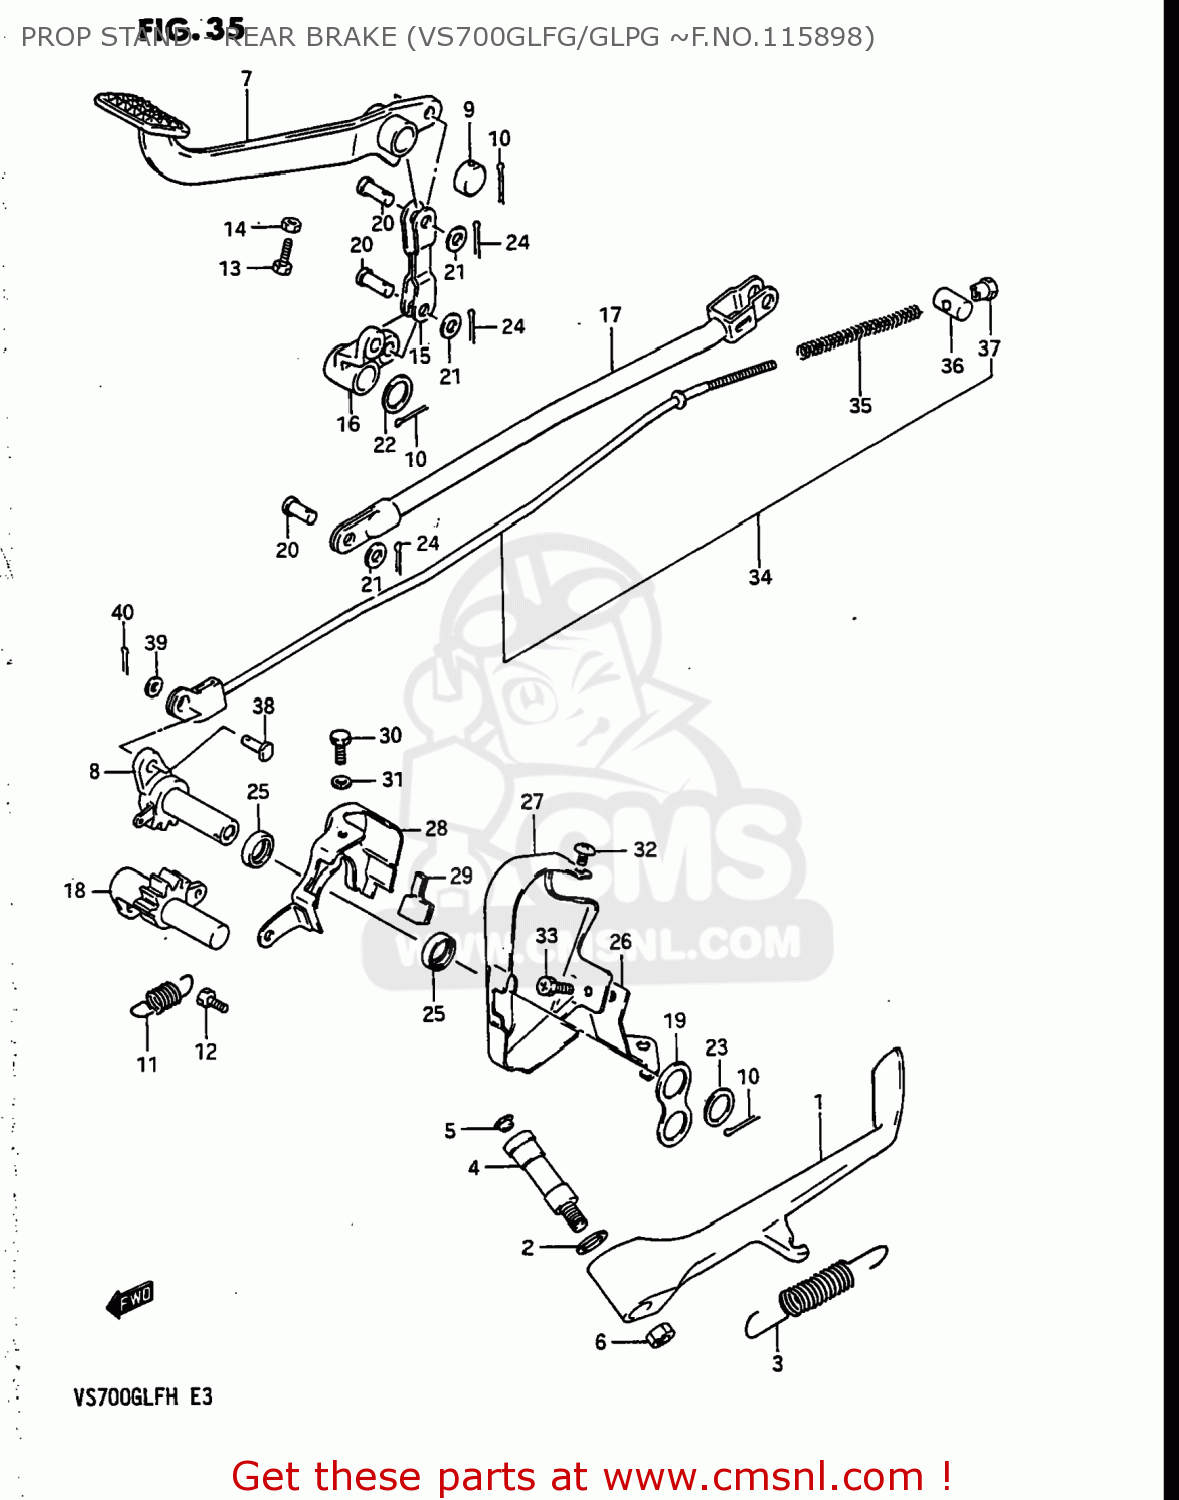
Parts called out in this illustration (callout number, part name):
1	STAND,PROP
2	THRUST WASHER
3	SPRING
4	BOLT,PROP STAND
5	CAP
6	NUT
7	PEDAL ASSEMBLY,BRAKE
8	ARM COMP,BRAKE ROD
9	CAP,BRAKE PEDAL
10	COTTER PIN
11	SPRING
12	ARM,BRAKE PEDAL LINK
13	BOLT
14	NUT
15	LINK COMP,BRAKE ROD NO
16	ARM,BRAKE PEDAL LINK
17	LINK COMP,BRAKE NO.2
18	ARM COMP,BRAKE PEDAL,LEFT
19	PLATE,BRAKE PEDAL ARM
20	PIN
21	WASHER
22	WASHER (16.5X42X2.6)
23	WASHER (17.2X30X1.6)
24	PIN
25	SEAL
26	BRACKET COMP,BRAKE ROD AR
27	COVER,BRAKE ROD ARM
28	COVER COMP,BRAKE ROD ARM
29	GROMMET,BRAKE COVER
30	BOLT
31	WASHER,LOCK
32	BOLT
33	SCREW(6X10)
34	ROD ASSEMBLY,REAR BRAKE
35	SPRING
36	PIN
37	NUT (6MM)
38	PIN
39	WASHER
40	PIN 20X20
